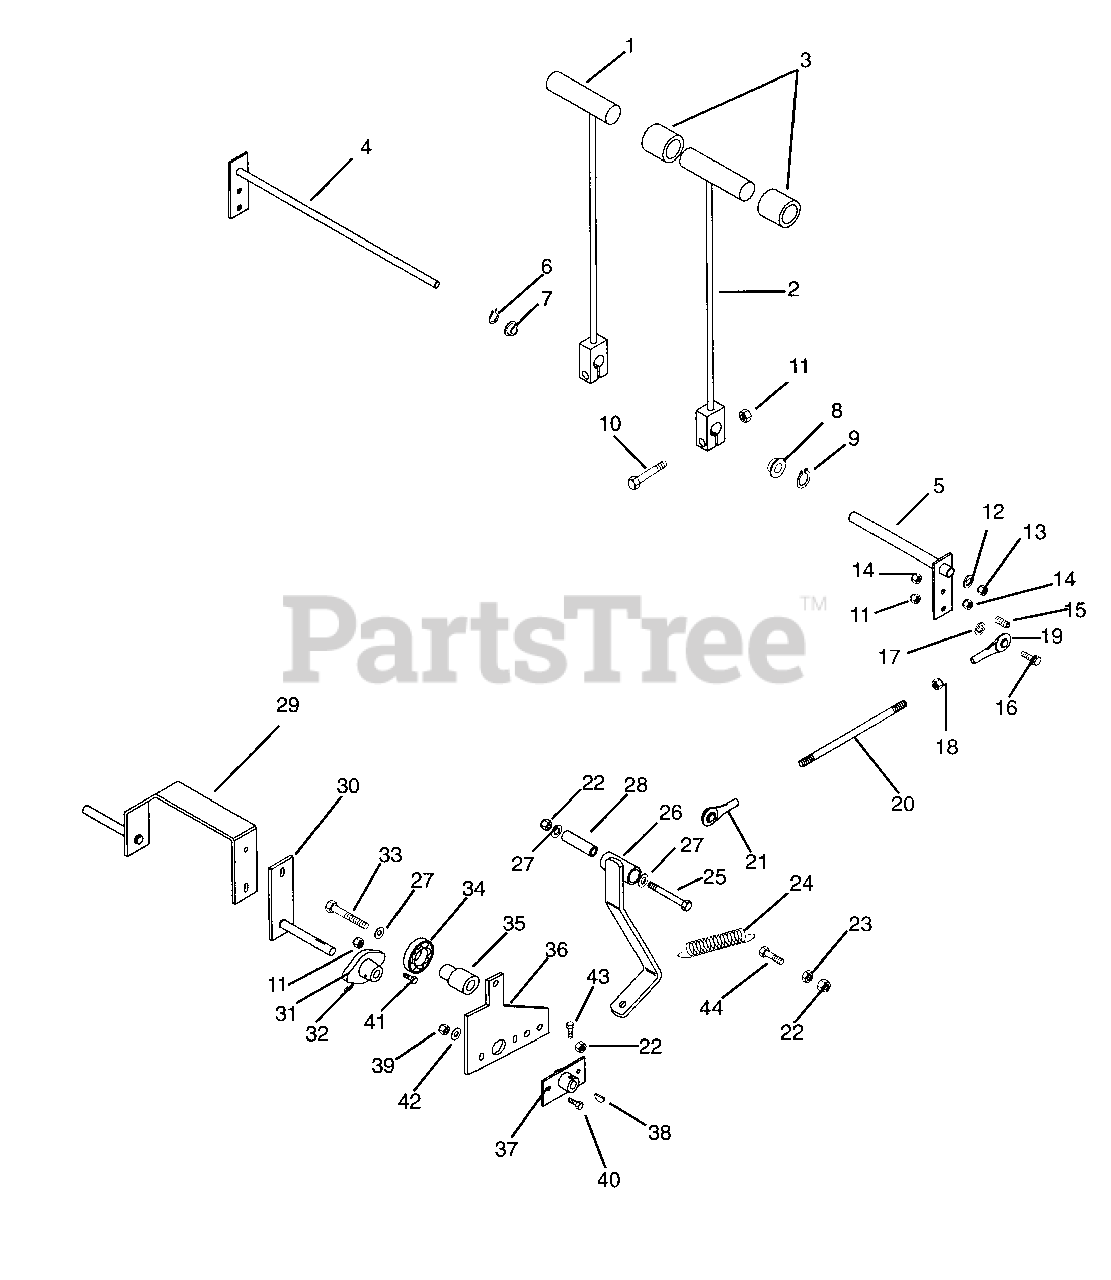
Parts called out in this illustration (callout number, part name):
1	Weldment-Steering Lever Left-Hand
2	Weldment-Steering Right-Hand
3	Grip-T-Bar
4	Weldment-Steering Rod
5	Weldment-Steering Tube
6	Ring-Retaining-External .500 x .460
7	Bushing-Flange .515 x .750 x .745 x 1.00
8	Bushing-Flange .762 x 1.0 x .580 x 1.48
9	Ring-Retaining-External .689 x .077
10	Bolt-Hex .31-18 x 1.50 Grade 5
11	Nut-Locking-Center .312-18
12	Washer-Flat-Steel .531 x 1.062 x .095
13	Nut-Locking-Center .50-13
14	Nut-Hex .31 - 18
15	Screw-Set .32-18 x 1.50
16	Bolt-Hex .31-18 x 1.25 Grade 5
17	Washer-Flat-Steel .344 x .688 x .065
18	Nut-Jam .375-24 (LH)
19	Rod End-Female 5/16"
20	Rod-Steering Adjusting
21	Rod End-Left Hand Female 5/16 - 24
22	Nut-Locking-Center .375-16
23	Nut-Hex .375-16
24	Spring-Tension .063 x .62 x 2.75
25	Bolt-Hex .38-16 x 2.75 Grade 5
26	Weldment-Neutral Detent
27	Washer-Flat-Steel .406 x .812 x .065
28	Bushing-Steel .385 x .610 x 1.80
29	Weldment-Pump Control Right-Hand
30	Weldment-Pump Control Left-Hand
31	Bushing-Flanged
32	Fitting-Lube .25-28 x .256
33	Bolt-Hex .38 - 16 x 2.00 Grade 5
34	Bearing-Ball .500 x 1.375 x .437
35	Hub-Bearing Mount
36	Arm-Speed Control
37	Arm-Speed Control
38	Key-Woodruff .13 x .75
39	Nut-Locking-Center .25-20
40	Bolt-Hex .50-20 x 1.00 Grade 8
41	Bolt-Hex .31-18 x 1.00 Grade 5
42	Washer-Flat-Steel .281 x .620 x .065
43	Bolt-Hex .25-20 x .50 Grade 5
44	Bolt-Hex .38-16 x 1.25 Grade 5
